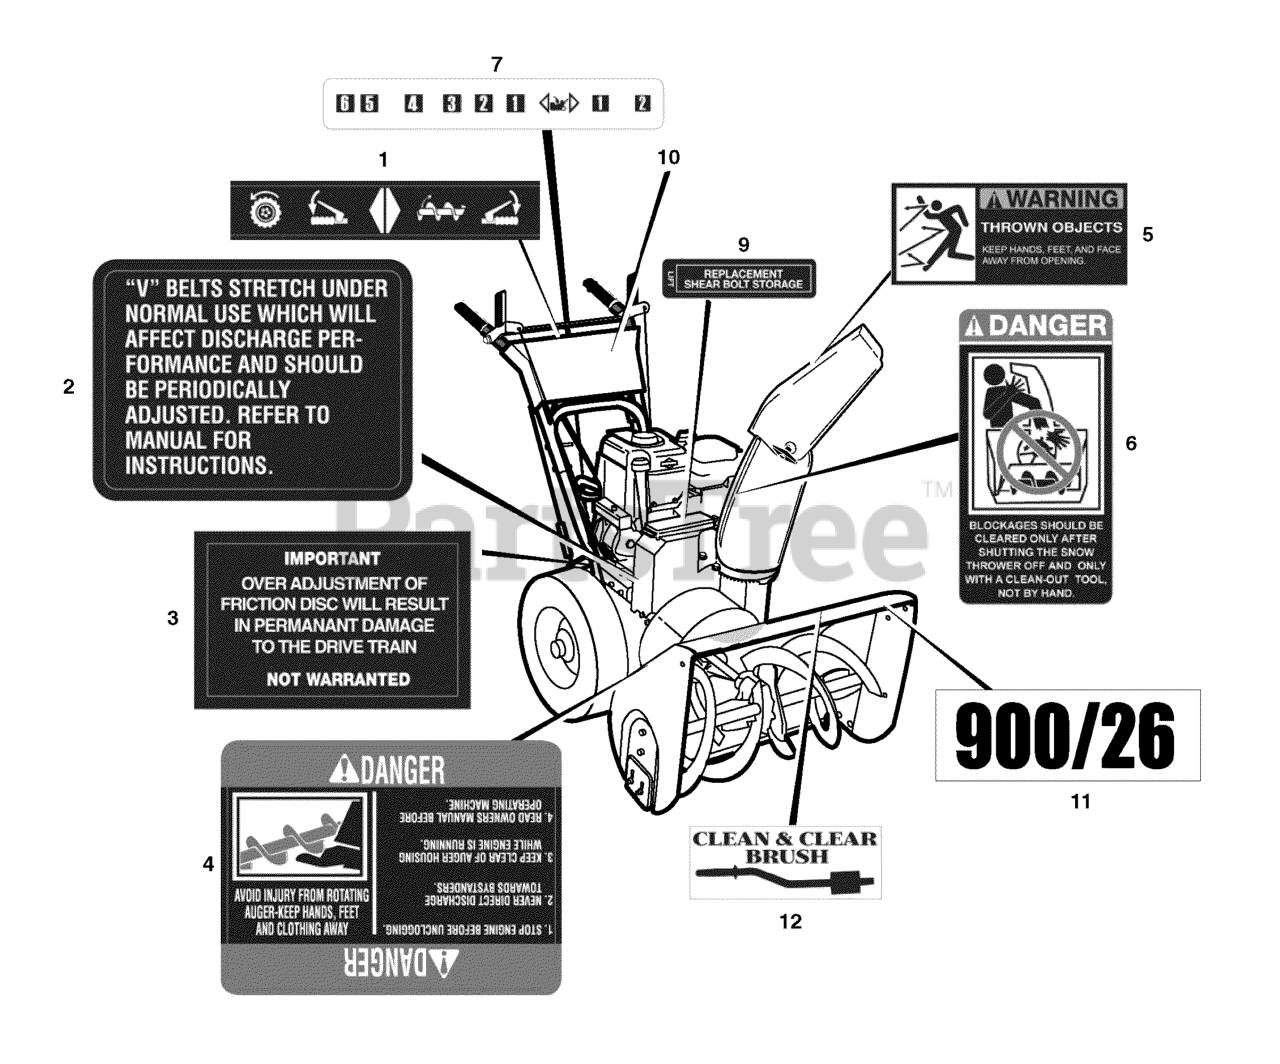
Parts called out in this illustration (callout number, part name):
1	DECAL, Hand Control
2	DECAL, V-Belts
3	DECAL, Over Adjustment
4	DECAL, Rotating Auger
5	DECAL, Thrown Objects
6	DECAL, Unclogging Chute
7	DECAL, Speed Control
9	DECAL, Shear Bolts
10	DECAL, Ultra Panel
11	DECAL, Murray Ultra 900/26
12	DECAL, Clean & Clear Brush
